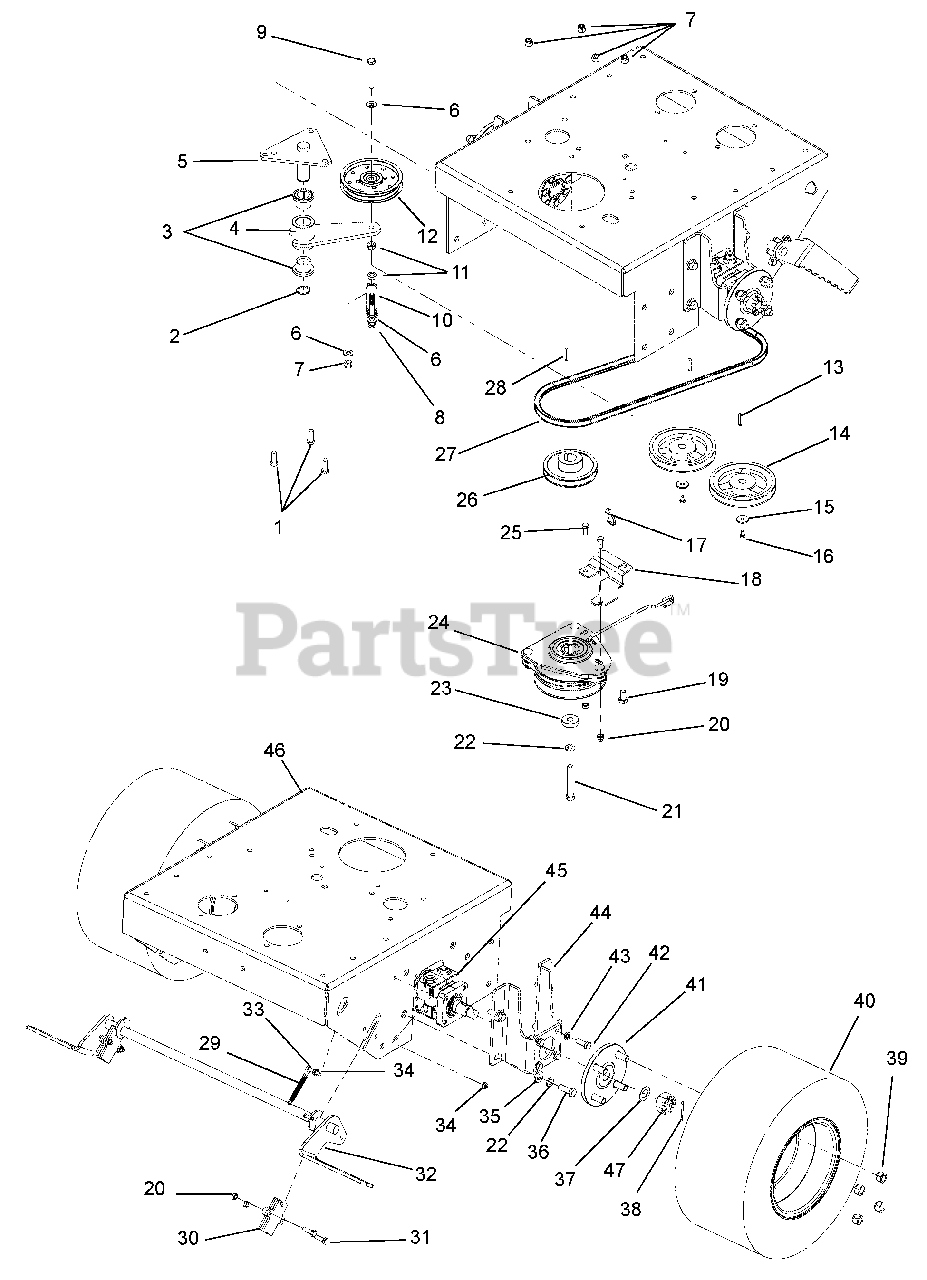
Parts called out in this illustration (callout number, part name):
1	BOLT, 3/8-16 X 1.00 HEX 5 Y
2	SNAP RING, 1.00 X .042 EXT
3	BRG, FLG 1.00 X 1.25 X 1.00
4	WLDT, IDLER ARM
5	WLDT, IDLER PIVOT MOUNT
6	WASHER, .406 X .813 X .065 FLAT Y
7	LOCKNUT, 3/8-16 NYLOC Y
8	BOLT, 3/8-16 X 3.00 HEX 8 Y
9	BOLT, 3/8-16 X 2.50 HEX 5 Y
10	SPRING, EXT .900X.135X4.50 Y
11	LOCKNUT, 3/8-16 WHIZ Y
12	PULLEY, FLAT 4.50 X .375 W/BRG
13	KEY, M5 X M5 X M30 RD
14	ASSY, PUMP PULLEY W/SET SCREW
15	WASHER, .250 WIDE HEAVY FLAT Y
16	BOLT, M6 X 1.00 X 10 HEX 8.8 Y
17	CABLE TIE, .15 X 8.50
18	PLATE, CLUTCH DOG
19	BOLT, 7/16-14 X .750 HEX 5 Y
20	LOCKNUT, 5/16-18 NYLOC Y
21	BOLT, 7/16-20X3.00 HEX 5 Y
22	WASHER, .438 MED SPRG LOCK Y
23	SPACER, .468 X 1.38 X .375 Y
24	CLUTCH ASSY, OGURA
25	BOLT, 5/16-18 X .750 HEX 5 Y
26	PULLEY, V-BELT 4.45X1.00 W/KEY
27	BELT, HA 55.1 EL AMD OHR
28	KEY, .250 X .250 X .995 TPR
29	SPRING, EXT .375 X .055 X 2.25 Y
30	SHOE, BRAKE SYSTEM FLOAT WALK
31	BOLT, 5/16-18 X 1.00 HEX 5 Y
32	WLDT, BRAKE SYS FLOAT HYDRO
33	BOLT, 1/4-20 X 1.25 HEX 5 Y
34	LOCKNUT, 1/4-20 WHIZ Y
35	WASHER, .468X1.00X.125 FLAT Y
36	BOLT, 7/16-14 X 1.25 HEX 5 Y
37	BUSHING, MACH .750X1.25X.048 Y
38	PIN, COT .125 X 1.50 EXTP Y
39	NUT, 1/2-20 LUG C
40	ASSY, WHEEL & TIRE - 16X6.5-8
41	ASSY, WHEEL HUB
42	BOLT, 3/8-16 X 1 GR8 BLACK
43	WASHER, .375 MED SPRG LOCK Y
44	BRKT, MOTOR MOUNT FLWLK
45	MOTOR, HYDRAULIC WHEEL
46	WLDT, ENGINE BED GRAVELY FLWLK
47	NUT, .75 UNF2B HEX SLOT JDS14
